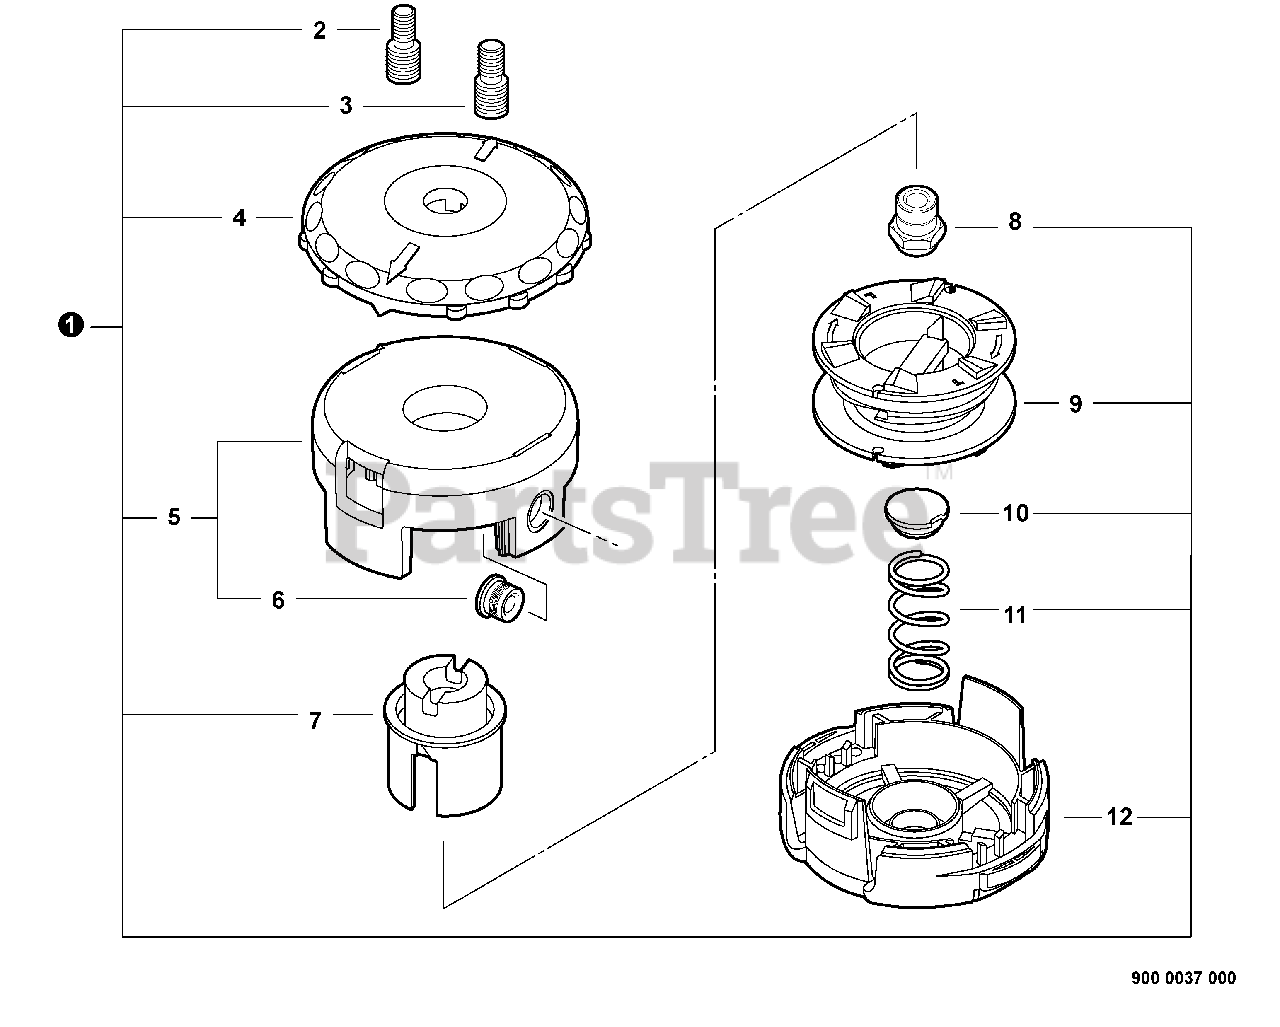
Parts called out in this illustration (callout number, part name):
1	SPEED-FEED 400 TRIMMER HEAD
2	STUD - GOLD -- LEFT HAND
3	STUD - SILVER -- LEFT HAND
5	SPOOL COVER ASSY
7	HUB - BLACK -- LEFT HAND
8	ARBOR - GOLD -- LEFT HAND
10	RETAINER, SPRING
